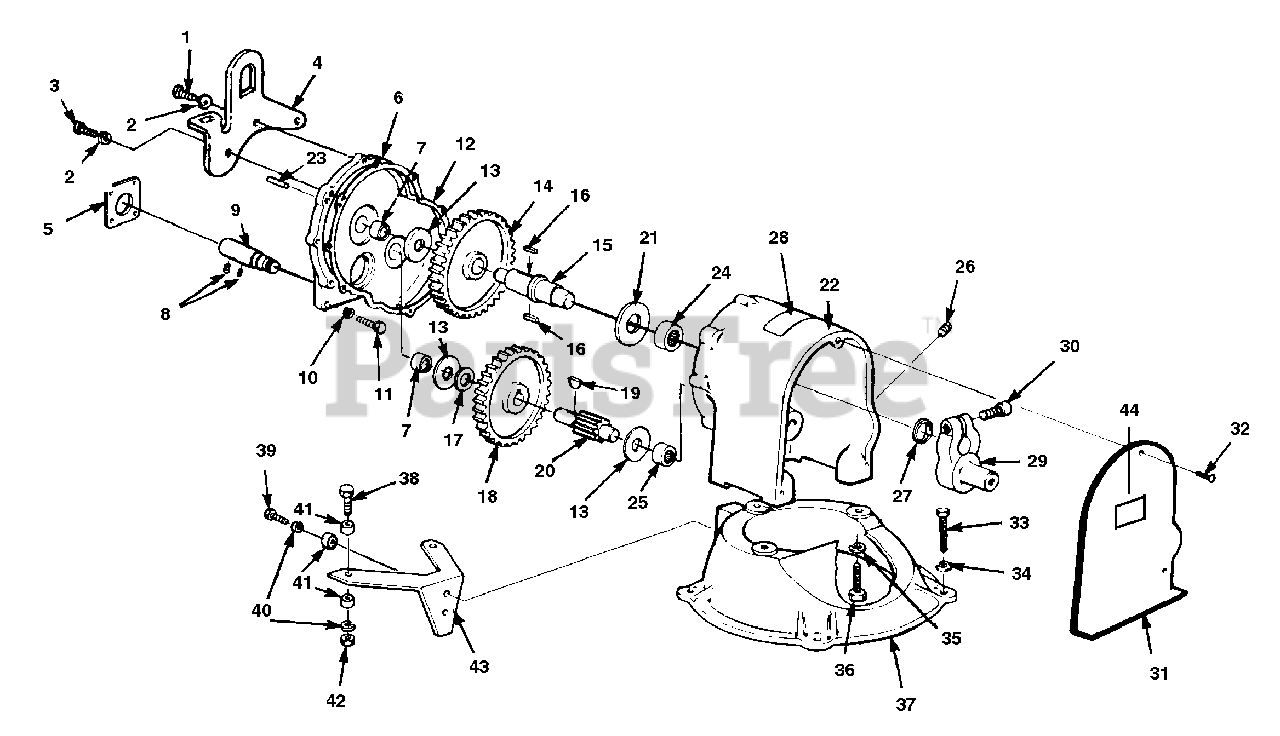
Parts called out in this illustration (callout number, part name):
1	SCREW-Hex Hd. (1/4-20 x 1 1/2")
2	WASHER - lock, 1/4
3	SCREW - hex hd., 1/4-20 x 1 1/4
4	BRACKET, lifting
5	GASKET-Engine mounting
6	COVER-Gear Case w/bearings
7	BEARING-Needle
8	SCREW-Set, 1/4-20 x 3/8 (Nylok)
9	SHAFT-Extension
10	WASHER-Lock (5/16")
11	SCREW 5/16 x 24 x 1.75
12	GASKET-Gear case
13	WASHER-Thrust, small
14	GEAR-Main
15	SHAFT-Drive
19	KEY-Woodruff, #61
20	SHAFT-Pinion
21	WASHER-Thrust, large
22	CASE-Gear w/bearings
23	PIN-Dowel
24	BEARING-Needle
25	BEARING-Needle
26	PLUG-Pipe
27	SEAL-Garlock
28	WARNING DECAL
30	SCREW-Cap (1/2-13 x 1 1/2")
31	SHIELD-Crank
32	SCREW-Thumb (1/4-20 x 1/2")
33	SCREW-Hex hd. (3/8-16 x 1 1/2)
34	WASHER-Lock (3/8")
35	WASHER-Lock (1/2")
36	SCREW-Hex hd. (1/2-13 x 1 3/4")
37	BODY-Pump (upper)
38	SCREW-Hex hd. (5/16-18 x 1 1/2")
39	SCREW-Hex hd. (5/16-18 x 7/8")
40	WASHER-Lock (5/16")
41	WASHER-Flat (5/16")
42	NUT-Hex (5/16-18)
43	SUPPORT-Engine
44	GREASE DECAL
